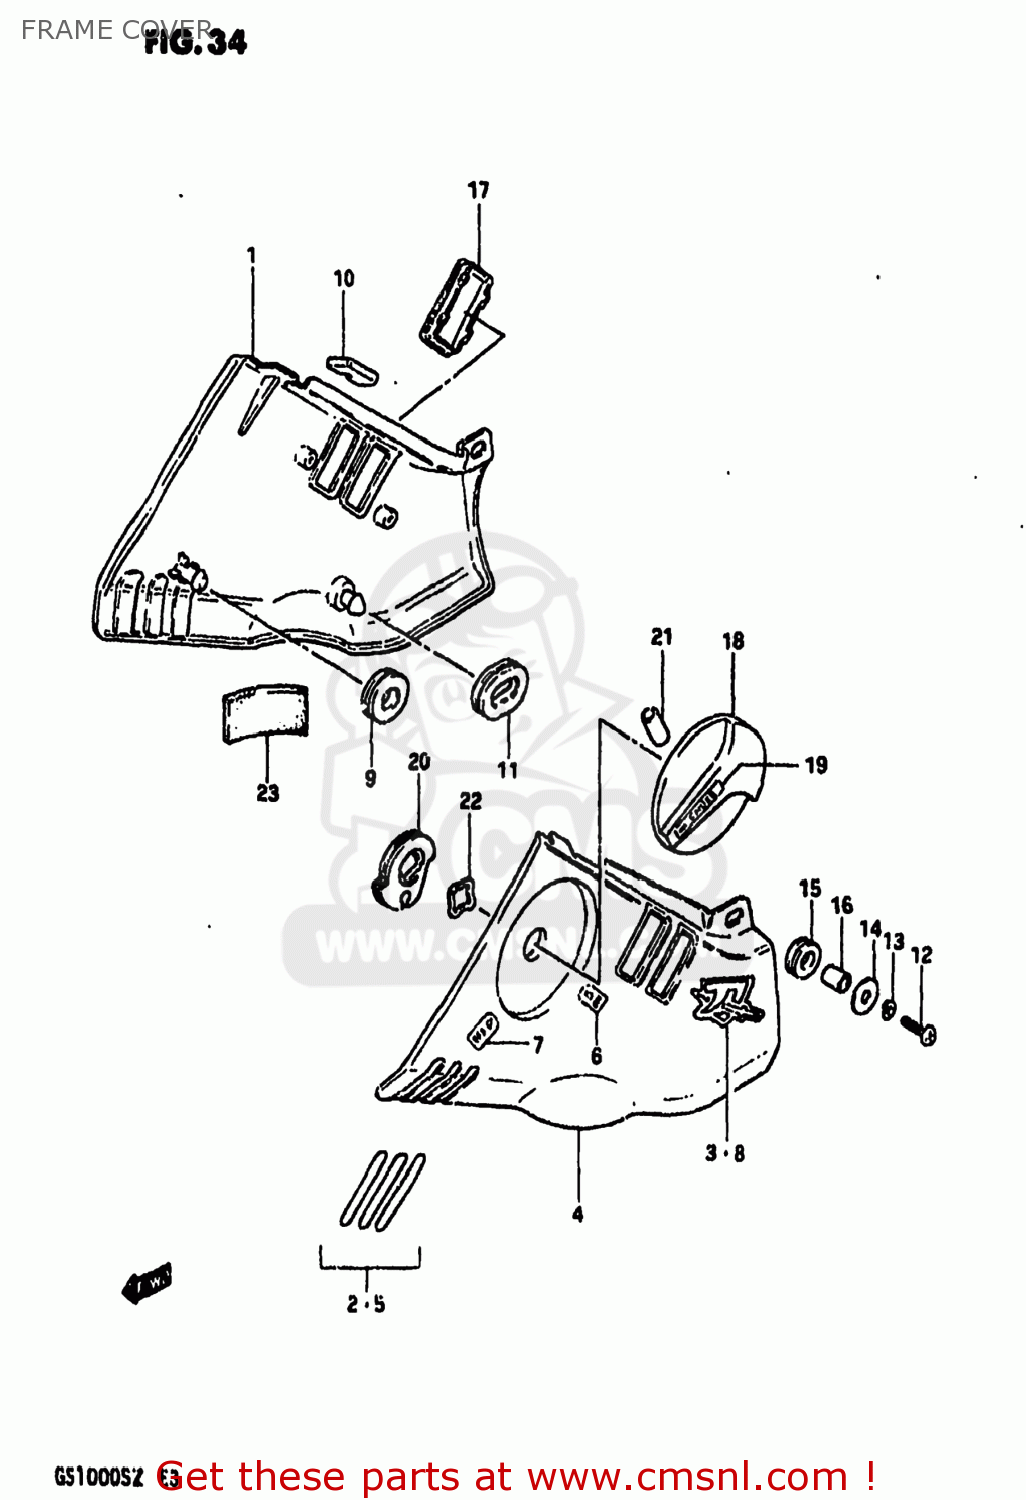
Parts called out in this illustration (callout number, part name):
1	COVER SET,FRAME,R(SILVER)
2	LABEL,FRAME COVER DENT
3	EMBLEM
4	COVER SET,FRAME,L(SILVER)
5	LABEL,FRAME COVER
6	LABEL,CHOKE ON
7	LABEL,CHOKE OFF
8	EMBLEM
9	CUSHION
10	CUSHION
11	CUSHION
12	SCREW
13	LOCK WASHER
14	WASHER
15	CUSHION
16	SPACER(6.1X9X7.5)
17	CAP,FRAME COVER SWITCH HOLE
18	LEVER,CHOKE CABLE
19	LABEL,CHOKE LEVER
20	HOLDER, STARTER
21	TUBE,CHOKE CABLE LEVER
22	WASHER
23	PAD
